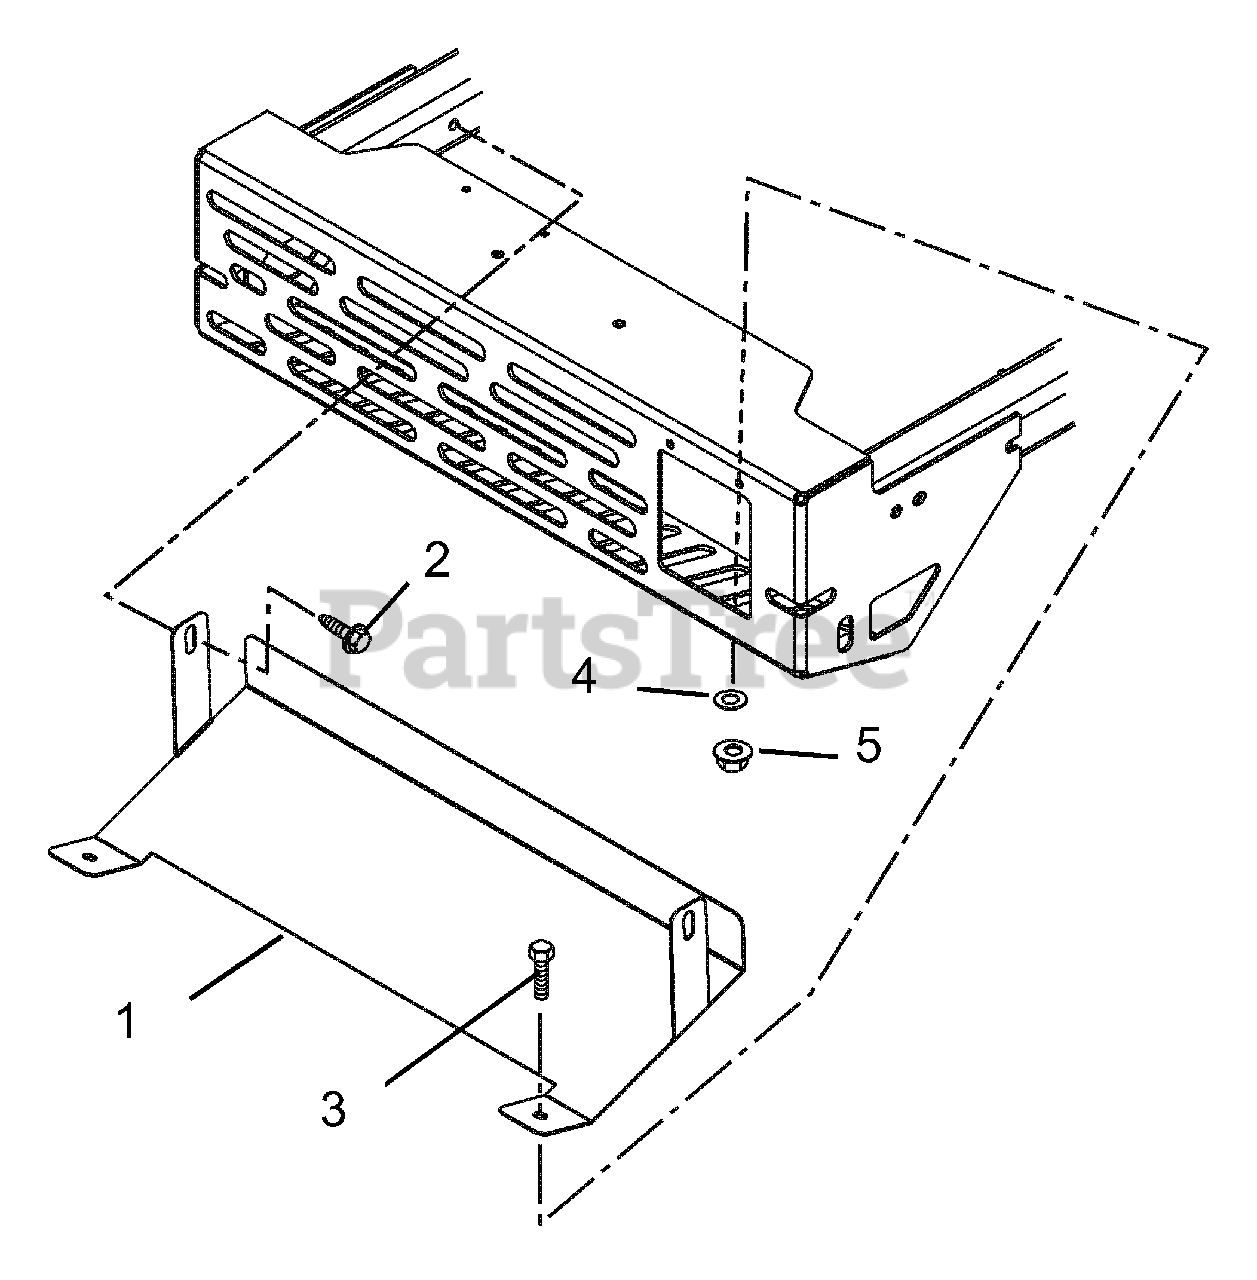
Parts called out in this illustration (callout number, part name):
1	Shield - Heat - MZ (Kit 592074)
2	.38-16 x .50" Hex Washer Head Tap Screws
3	.38-16 x 75 Hex Bolt
4	.438" x 1.00" x .083" Flat Steel Washer
5	.38-16 top Flange Lock Nuts
